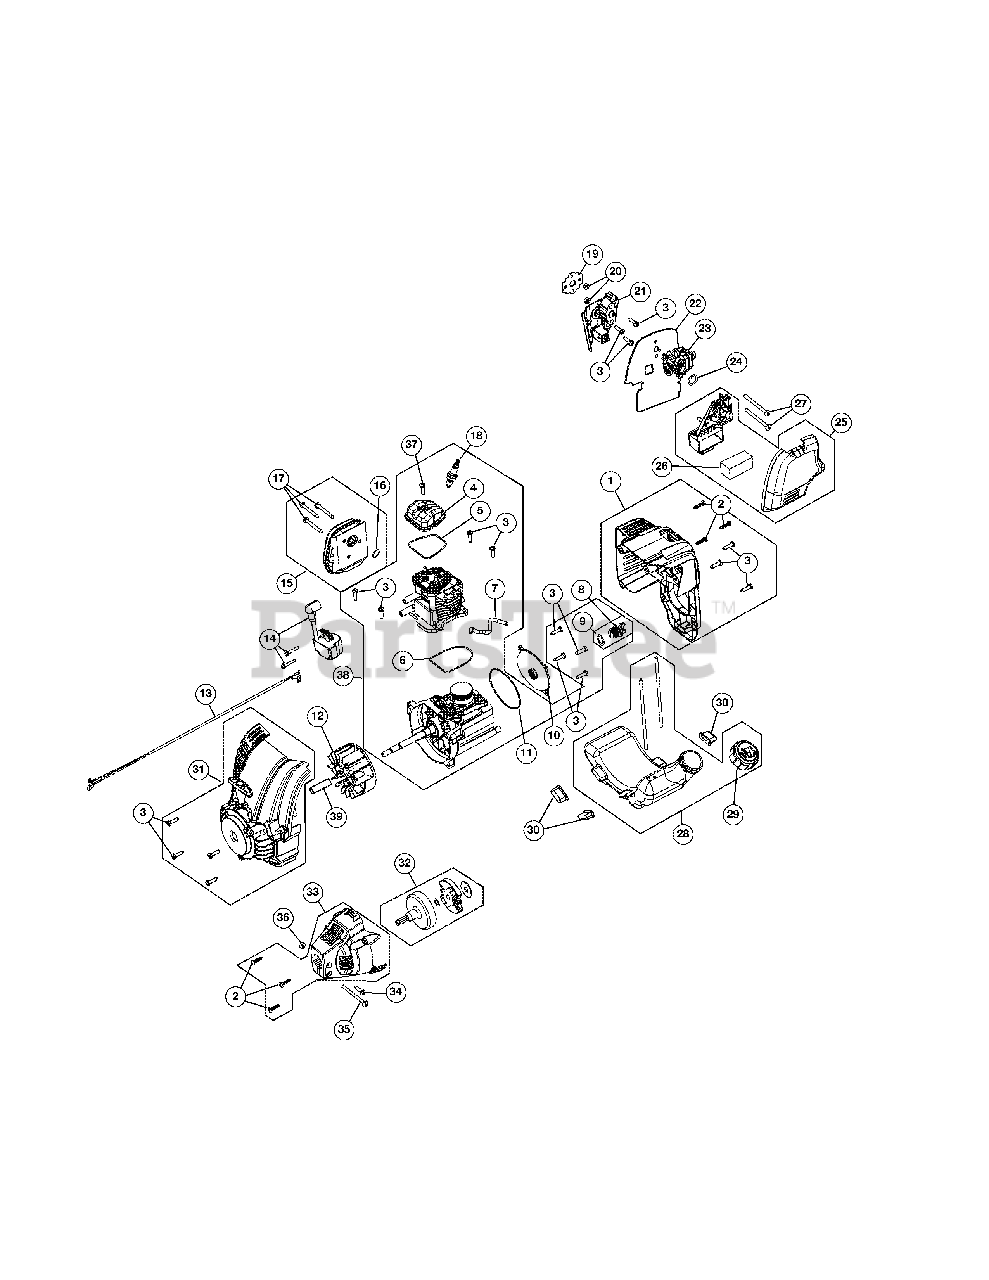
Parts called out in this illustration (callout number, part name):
1	Engine Cover Assembly (Incl Ref No.2 & 3)
2	Cover Screw
3	Screw
4	Rocker Cover
5	Rocker Cover O-Ring
6	Cylinder O-Ring
7	Breather Hose
8	Oil Plug (Incl Ref No.9)
9	Oil Plug O-Ring
10	Crankcase Cover
11	Crankcase Cover O-ring
12	Flywheel Assembly
13	Lead Wires
14	Module Assembly
15	Muffler Assembly (Incl Ref No.16 & 17)
16	Muffler Gasket
17	Muffler Screw
18	Spark Plug
19	Insulator Gasket
21	Insulator
22	Carburetor Gasket
23	Carburetor w/Primer
24	Air Cleaner O-Ring
25	Air Cleaner Cover Assembly (Incl Ref No.26)
26	Air Filter
28	Fuel Tank Assembly w/Fuel Lines (Incl Ref No.29)
29	Fuel Cap
30	Fuel Tank Pads
31	Starter Housing Assembly (Incl Ref No.3)
32	Clutch Assembly
33	Clutch Cover (Incl Ref No.2)
34	Anti-Rotation Screw
35	Clamp Screw
37	Rocker Cover Screw
38	Shortblock Assembly
39	Spacer
